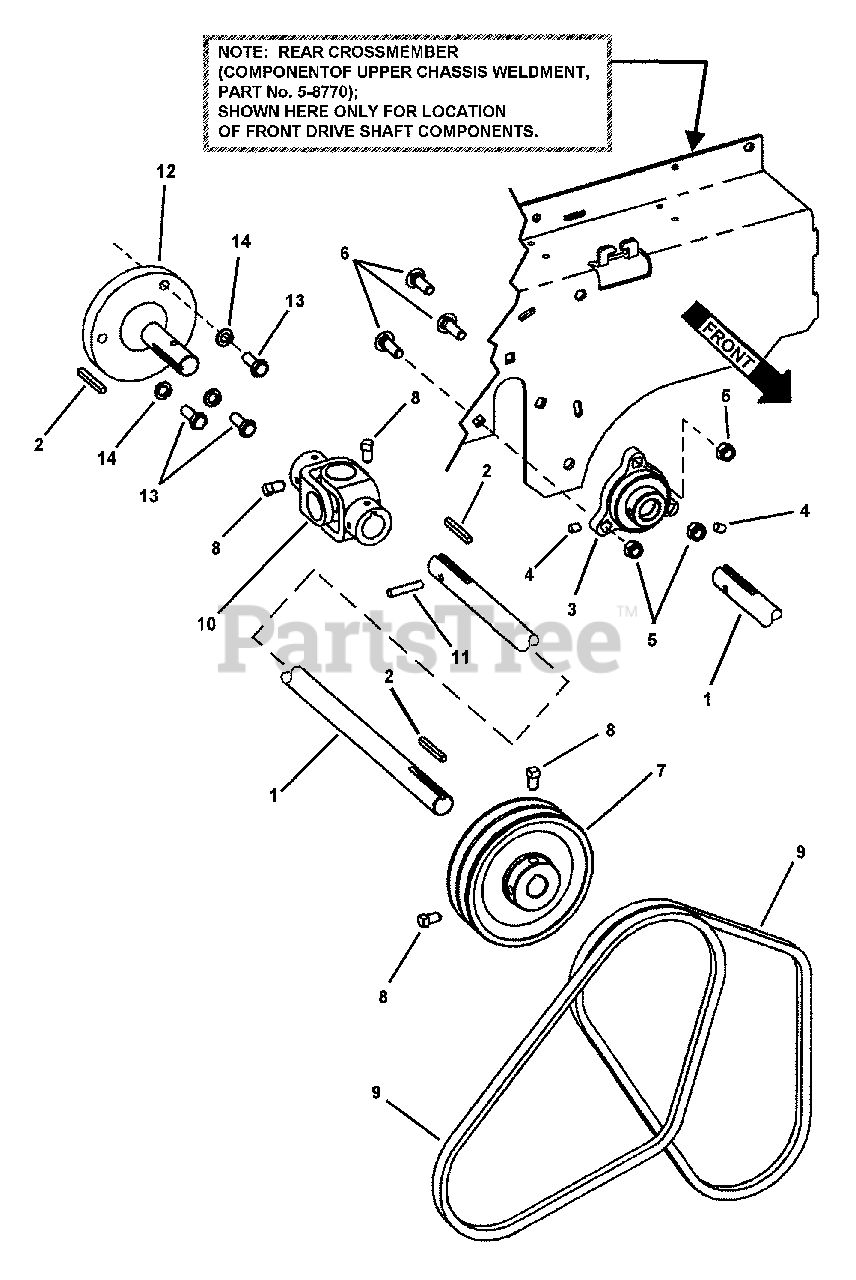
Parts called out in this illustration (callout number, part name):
1	PTO SHAFT, 3/4" Dia. x 16" Long
2	KEY, 3/16 Square x 1-1/2" Long
3	ASSEMBLY, Bearing/Lock Collar
4	SET-SCREW, 1/4-20 x 5/16" Socket-Head
5	NUT, 5/16-18 HEX NYLON LOCK
6	BOLT, 5/16-18 x 1" Round Head Square Neck, Grade 5
7	PULLEY, Cast Iron Dual V, 49.5 Effective O.D.
8	SET-SCREW, 5/16-18 x 1/2", Square-Head Cup Point
9	BELT, 36-1/2"
10	COUPLING, Universal
11	GROOVE PIN, 7/32 x 1-1/4"
12	ADAPTER, Engine/U-Joint
13	SCREW, M8-1.25 x 20 Hex Head Cap
14	WASHER, .32 I.D. Split Lock
